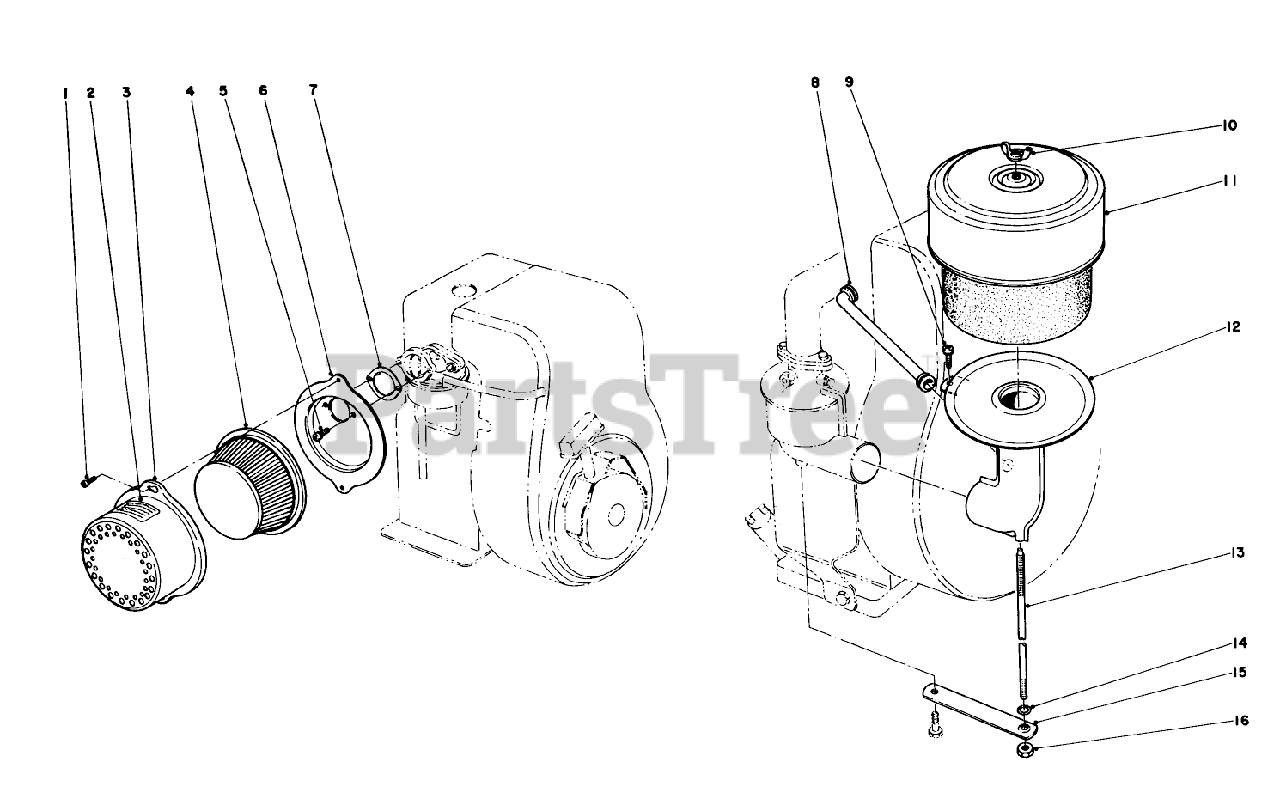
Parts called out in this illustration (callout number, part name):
1	Screw
2	Decal
3	Body
4	Element
5	Screw (10-32 x 1/2)
6	Bracket
7	Gasket
8	Tube Breather
9	Screw
10	Wing Nut
11	Cleaner Assy.-Air
12	Pipe Tube Assembly
13	Stud
14	Gasket-O-Ring
15	Strap
16	Nut
